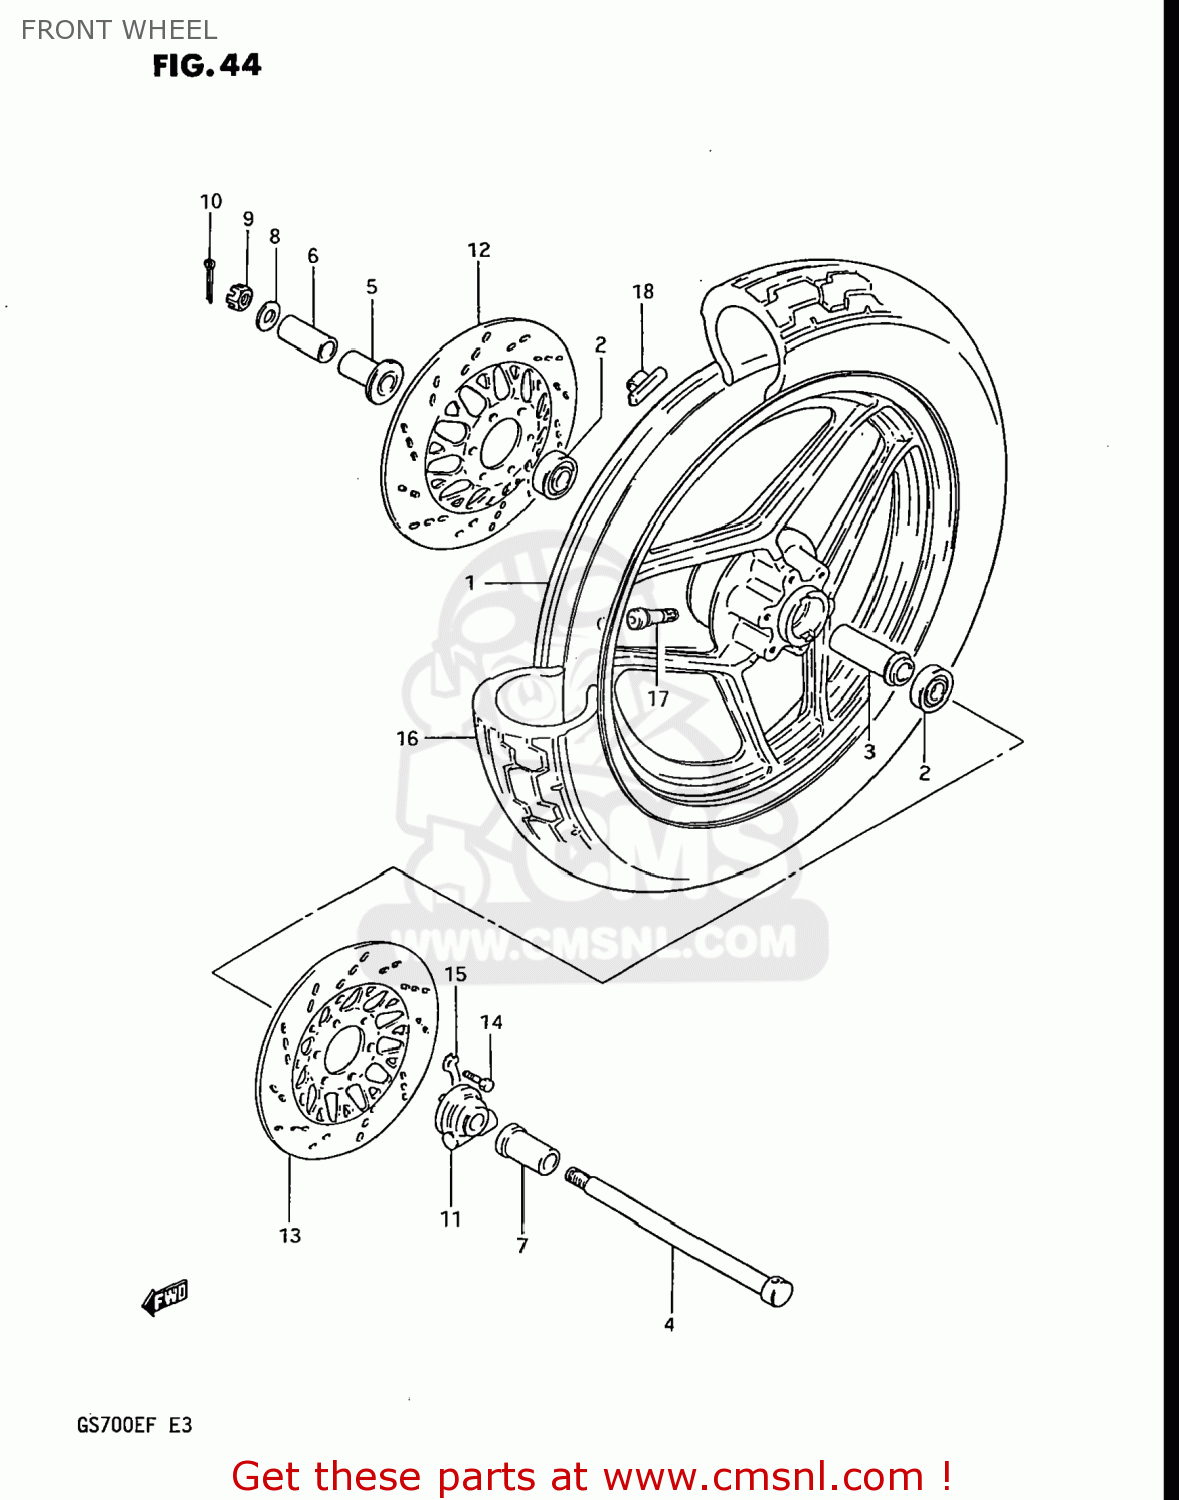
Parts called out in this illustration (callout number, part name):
1	CASTING WHEEL,FRONT 2.15
2	BEARING
3	SPACER,FRONT HUB BEARING
4	AXLE,FR
5	SPACER,FR AXLE,R
6	SPACER,FR AXLE,R
7	SPACER,FR AXLE,L
8	WASHER
9	NUT 12MM
10	COTTER PIN
11	BOX ASSEMBLY,SPEEDOMETER GEAR
12	DISC,BRAKE,RIGHT
13	DISC,BRAKE,LEFT
14	BOLT(8X25)
15	WASHER
16	TIRE,FRONT
17	VALVE,TIRE
18	BALANCER,WHEEL
